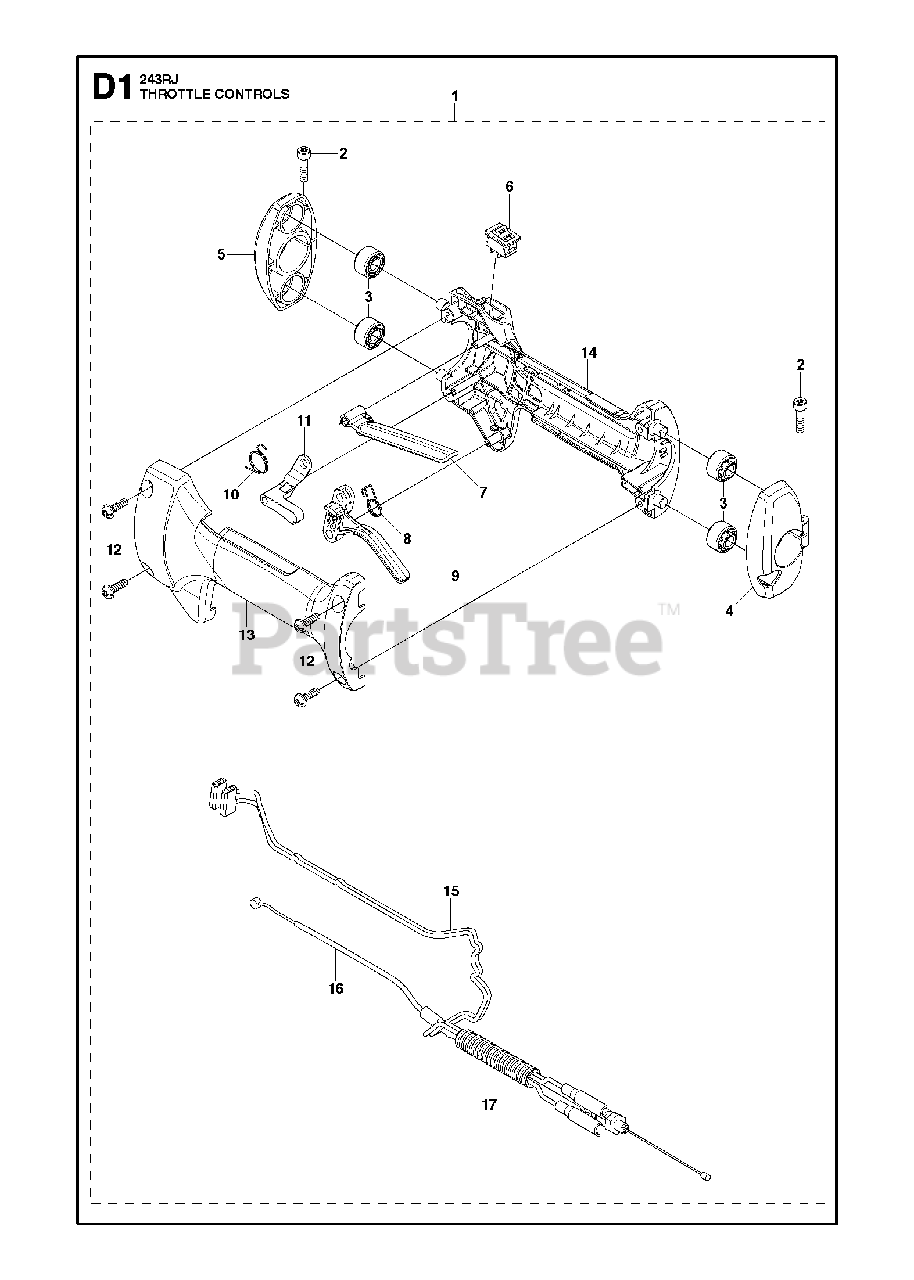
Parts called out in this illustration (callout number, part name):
2	BOLT
6	SWITCH
10	SPRING
12	SCREW
